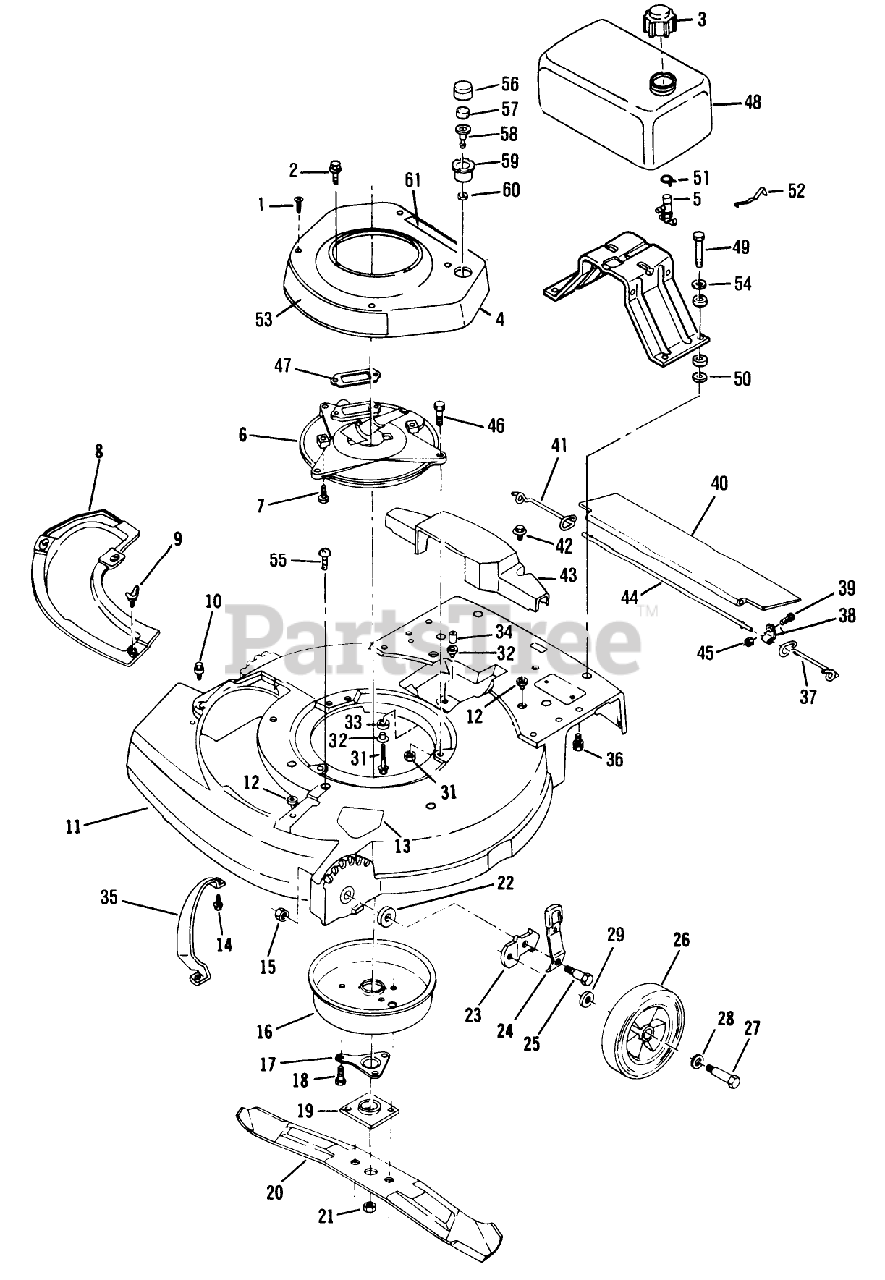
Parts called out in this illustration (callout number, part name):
1	SCREW - SELF TAPPING
2	SCREW SEMS SM
3	Fuel Cap
5	VALVE&SCREEN SM
6	PLATE F
7	SCREW V
9	WING SCREW LAWRE
15	LOCKNUT
16	MUFFLER COVER F
17	SUPPORT F
18	SCREW
19	PLATE AND COLLAR ASM
21	NUT-BLADE
22	WASHER
25	BOLT
27	BOLT-SHOULDER
28	SPACER
29	WASHER WROUGHT
30	NUT-LOCK F
32	SPACER ECK PRES
33	GROMMET
34	SPACER
35	BAR-TOE
36	SCREW
37	SPRIG T/SHLD ASOC
38	CLAMP ROD KMC
40	SHIELD
41	SPRING;TRAILING SHIELD RH
42	SCREW SEMS TRM HEX HD
43	COVER
44	ROD 21" ADVANCE
45	LOCKNUT E
46	SCREW-HH
48	TANK - FUEL
49	BOLT PIONEER
51	CLAMP - HOSE S
52	SPRING
54	WASHER
57	FILTER S
58	BASE P'MERBULB S
59	CUP PRIMER S
